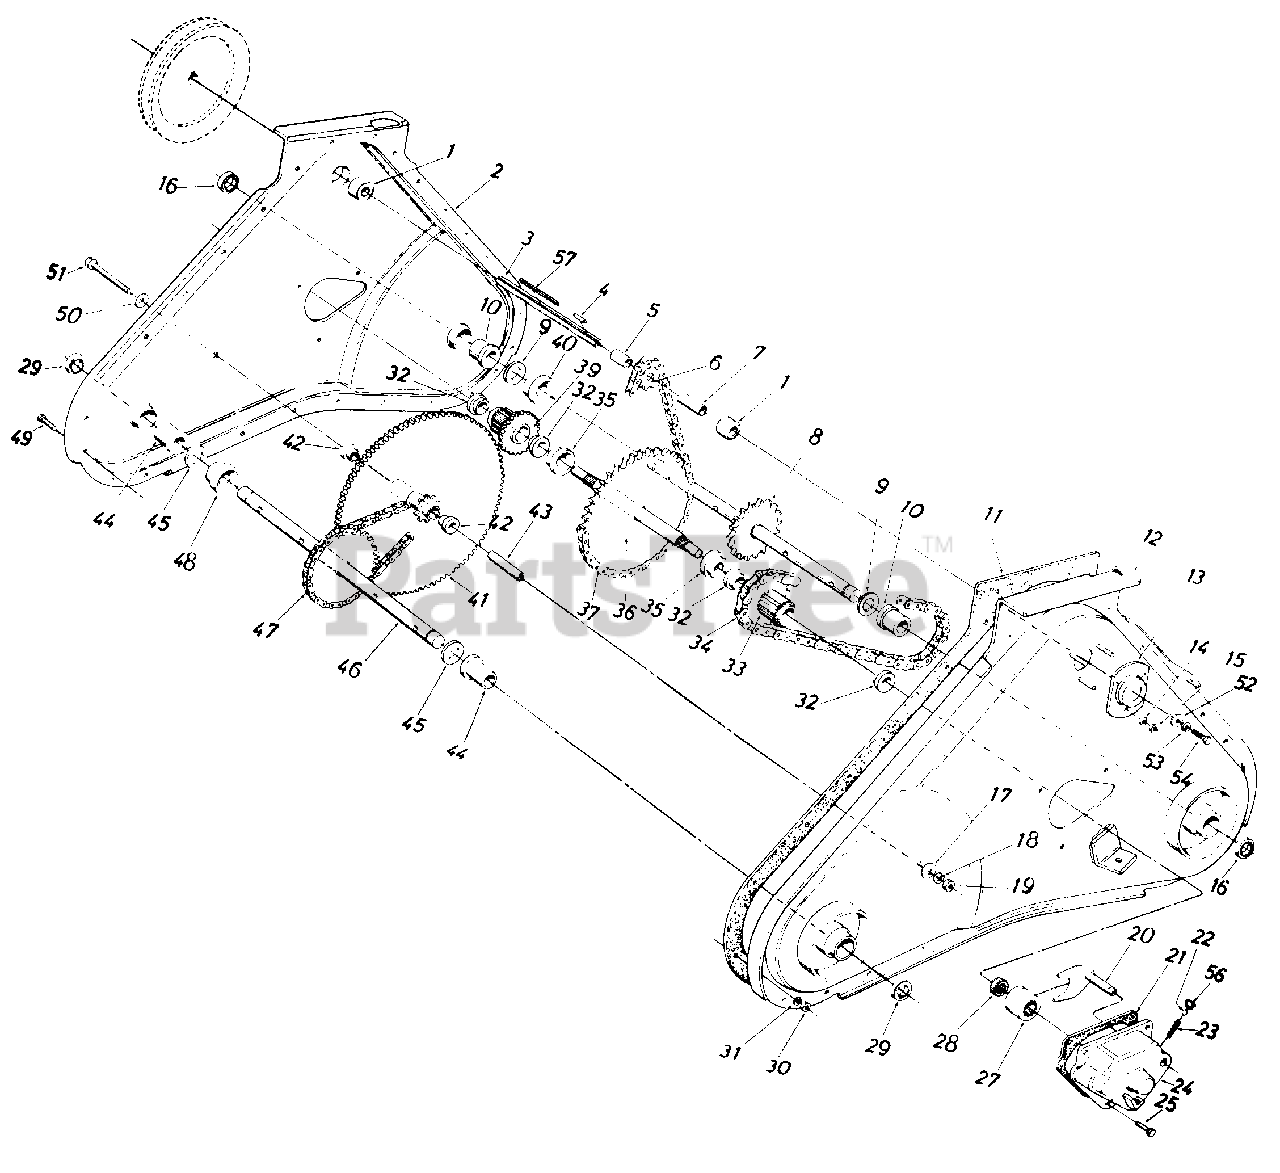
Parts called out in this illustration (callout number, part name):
1	Ball Bearing .62" I.D. x 1.38" O.D. x .44
2	Chain Case R.H. Half
3	Input Shaft .62" Dia.
4	Sq. Key 3/16" x 3/16" x .75"
5	Spacer .637" I.D. x .781" O.D. x .85" Lg.
6	Sprocket 9 Tooth x .62" Shaft
7	Spacer .637" I.D. x .781" O.D. x 1.44" Lg.
8	Tine Shaft Ass'y.
9	Fl-Wash. 1.28" I.D. x 1.62" O.D.
10	Flange Bearing 1.25" I.D.
11	Gasket-Housing
12	Chain Case L.H. Half
13	Bearing Housing 1-3/8" O.D.
14	L-Wash. 1/4" I.D.
15	Hex Nut 1/4-28 Thd.
16	Seal 1.25" I.D.
17	Belleville Wash.
18	L-Wash. 3/8" I.D.
19	Hex Cent. L-Nut 3/8-24 Thd.
20	Shift Yoke Ass'y.-L. H.
21	Gasket-Shift Housing
22	Ball Detent .250 Dia.
23	Compression Spring
24	Shift Housing-L.H.
25	Hex Tap-Tite 5/16-18 x .75" Lg.
27	Clutch Dog
28	Clutch Dog Driver
29	Seal 1.0" I.D. x 1.38" O.D.
30	Hex Nut 1/4-28 Thd.
31	L-Wash. 1/4" I.D.
32	Flange Brg. 1.00" I.D.
33	Sprocket Brg. Sleeve Ass'y.
34	#50 Chain-5/8" Pitch x 50 Links-Endless
35	Stepped Spacer 1.0" I.D. x 1.75" O.D.
36	Clutch Shaft Ass'y.
37	#420 Chain 1/2" Pitch x 58 Links-Endless
39	Gear Bearing-Sleeve Ass'y.
40	Spacer 1.25" I.D. x 2.0 O.D. x .68" Lg.
41	Sprocket and Gear Ass'y.
42	Flange Brg. .628" I.D. x .753" O.D.
43	Hub Sleeve .38" I.D. x .625" O.D.
44	Flange Brg. 1.00" I.D. x 1.188" O.D.
45	Fl-Wash. 1.0" I.D. x 1.62" O.D.
46	Axle Shaft Ass'y.
47	#420 Chain 1/2" Pitch 46 Links-Endless
48	Spacer 1.0" I.D. x 2.0" O.D.
49	Hex Bolt 1/4-28 x .62" Lg.
50	Belleville Wash.
51	Hex Bolt 3/8-24 x 2.75" Lg.
52	Fl-Wash. 5/16" I.D.
53	L-Wash. 5/16" I.D.
54	Hex L-Bolt 5/16-24 x .75" Lg.
56	Cap Plug .250" Dia.
57	Sq. Key 3/16" x 2.0" Lg.
